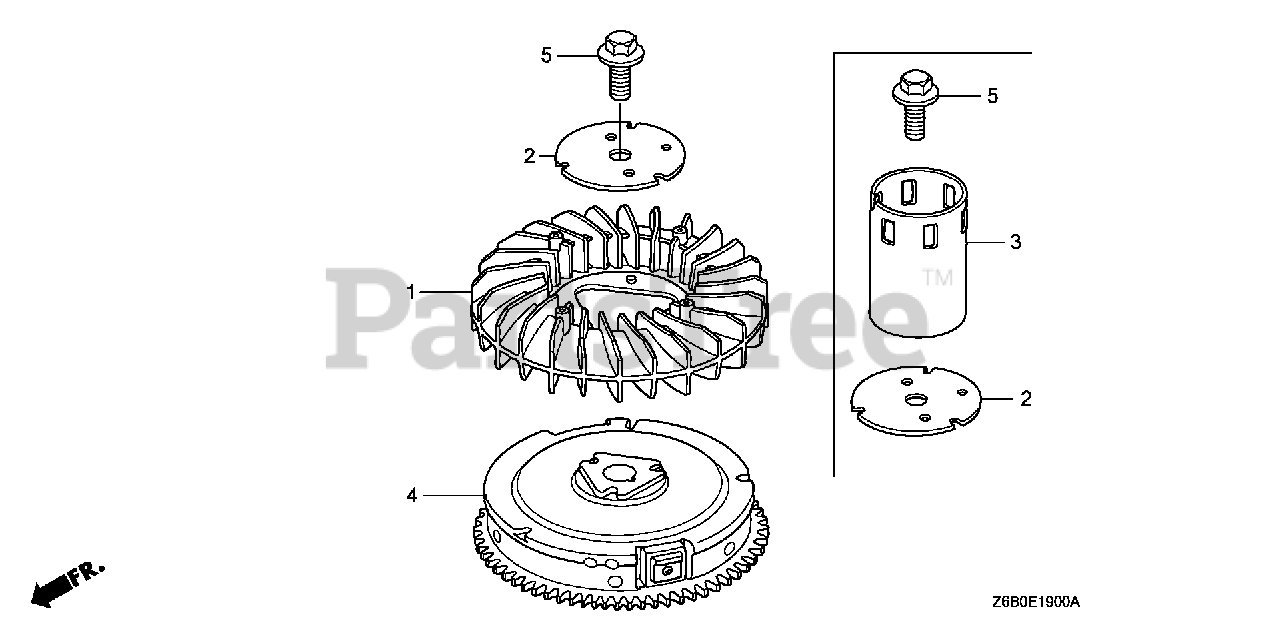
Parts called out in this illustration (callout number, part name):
1	FAN, COOLING
2	PLATE, COOLING FAN SETTING
4	FLYWHEEL (6P)
5	BOLT, FLANGE (16X35)
